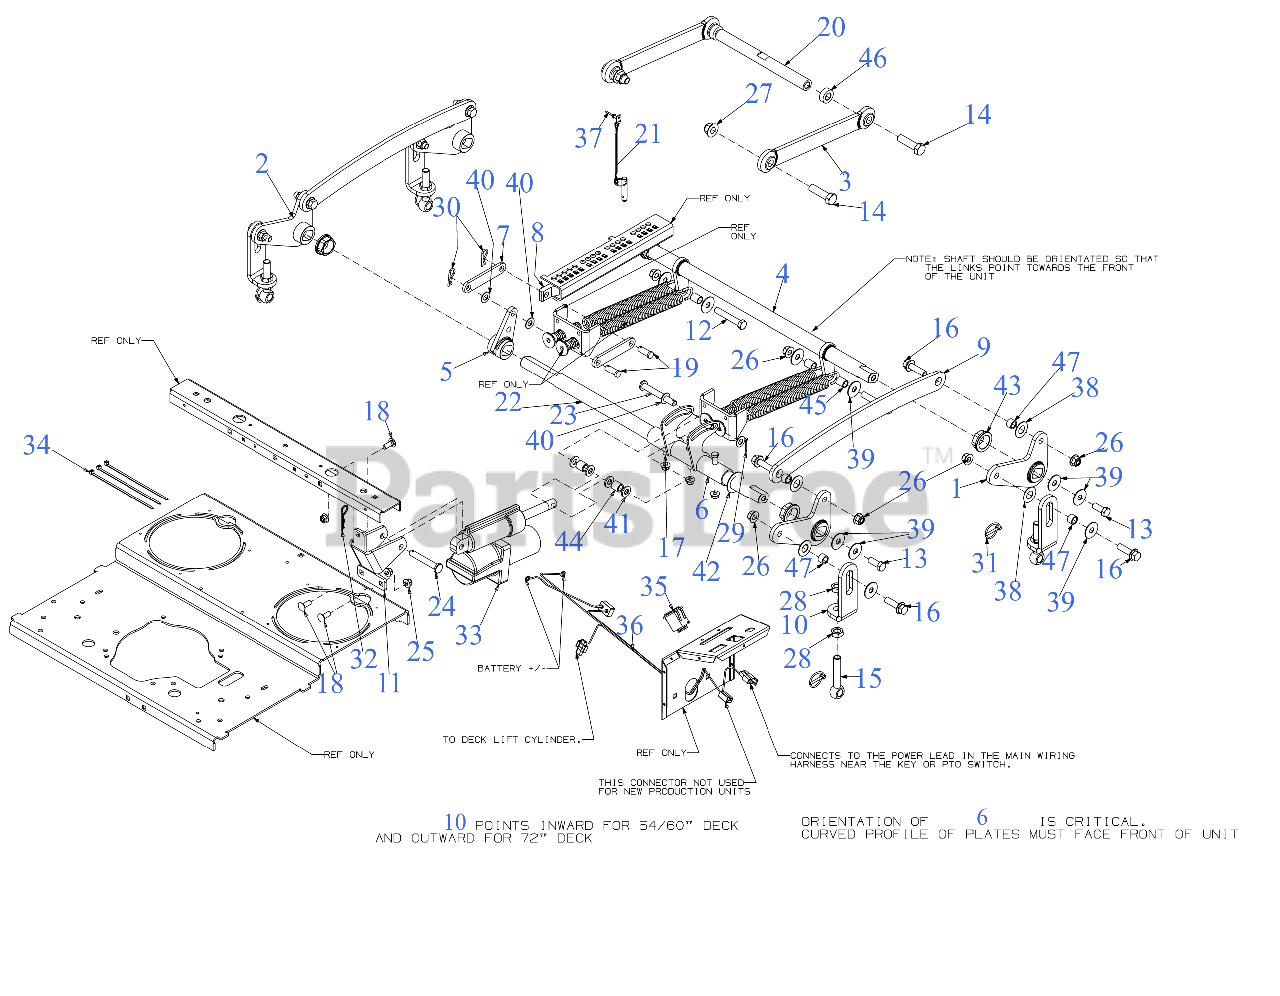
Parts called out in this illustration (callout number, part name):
4	FRONT DECK LIFT SHAFT
5	DECK LIFT HUB ASSEMBLY (LH)
6	LIFT BRACKET
7	DECK LIFT INDEX LINK
8	LIFT INDEX SLIDER ARM
12	SCREW-HEX 1/2-13 x 3.00
13	SCREW 1/2-13 x 1.25 GR5
14	SCREW 5/8-11 x 2.25 GR5
15	EYE BOLT 5/8-11 x 3.63
16	FLANGE BOLT 1/2-13:1.75:GR5
17	SCREW 3/8-16 x 2.0 GR5
18	CARRIAGE BOLT 3/8-16 x 1.00 GR5
19	CLEVIS PIN .500 x 1.25
20	FRONT LIFT SHAFT
21	DETENT PIN
22	LIFT SHAFT 1.25 DIA
23	CLEVIS PIN
24	CLEVIS PIN .50"OD
27	FLANGE LOCK NUT
28	HEX JAM NUT
29	COTTER PIN-1/8 DIA x 1.00
30	COTTER PIN
31	LYNCH PIN .1875
32	COTTER PIN .125X2.
33	ELEC/HYD LIFT CYLINDER
34	7" CABLE TIE
35	DECK LIFT SWITCH
36	ELECTRIC DECK LIFT WIRING HARNESS
37	FULL TUBULAR RIVET
38	FLAT WASHER .760ID X1.49OD x .06
39	FLAT WASHER
40	FLAT WASHER .510X.995
41	FLAT WASHER
42	THRUST WASHER 1.25X1.94X.063 7000
43	FLANGE BEARING
45	SPACER 0.535 x 0.68 x 0.83
46	SPACER .635X1.25X.445
